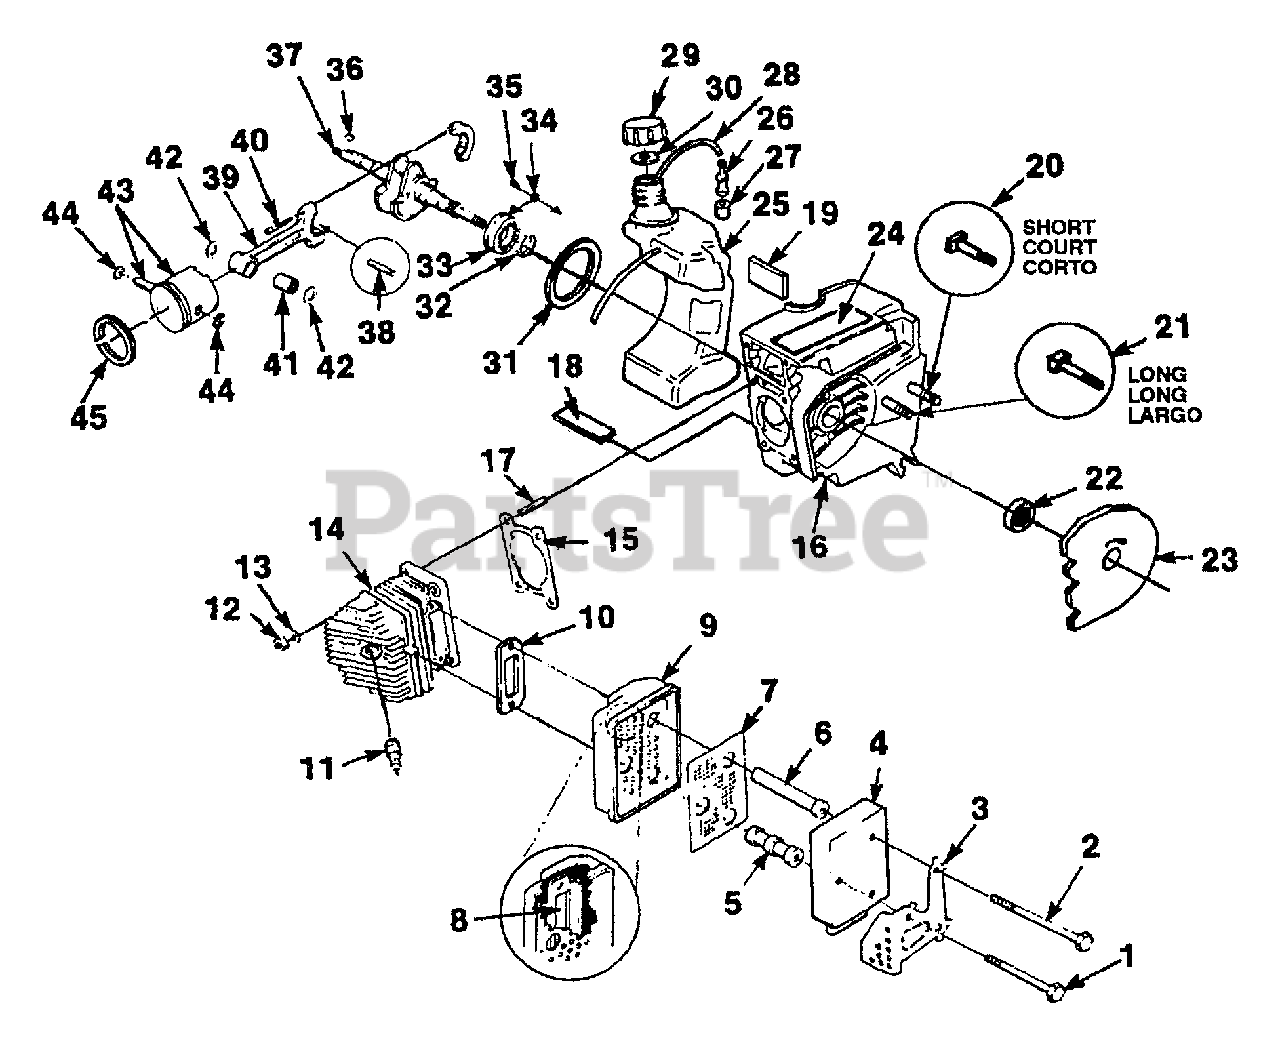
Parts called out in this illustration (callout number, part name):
1	SCREW-Hex Hd.
2	SCREW-Hex Hd. (1/4-20 X 3")
3	SHIELD- Muffler
4	CAP- Muffler
5	SUPPORT-Short
6	SUPPORT-Long
7	SCREEN-Spark Arrestor
8	PLATE-Muffler
9	BODY- Muffler
10	GASKET-Muffler
11	SPARK PLUG
12	NUT-(1/4-28 X 3/8")
13	WASHER- Lock (1/4")
14	CYLINDER
15	GASKET-Cylinder
16	CRANKCASE
17	STUD-Cylinder
18	SPACER-Fuel Tank
19	SPACER-Fuel Tank
20	BOLT-(3/8-16 X 2 1/8")
21	BOLT-(3/8-16 X 2 11/32")
23	SAW DUST SHIELD
24	DECAL-Instruction/Warning
25	FUEL TANK
26	FILTER-Fuel
27	ELEMENT-Filter
28	TUBING-Rubber (13")
29	CAP-Fuel
30	GASKET-Fuel
31	"O" RING
32	RING-Retaining
33	BEARING-Ball
34	WASHER-Lock
35	SCREW-Torx (10-32)
36	KEY-Woodruff
37	CRANKSHAFT
38	BEARING-Needle
39	ROD-Connecting
40	SCREW-Hex Hd. (8/32 X 1/2")
41	BEARING
43	PISTON & PIN ASSY.
44	RING-Retaining
45	PISTON RING
